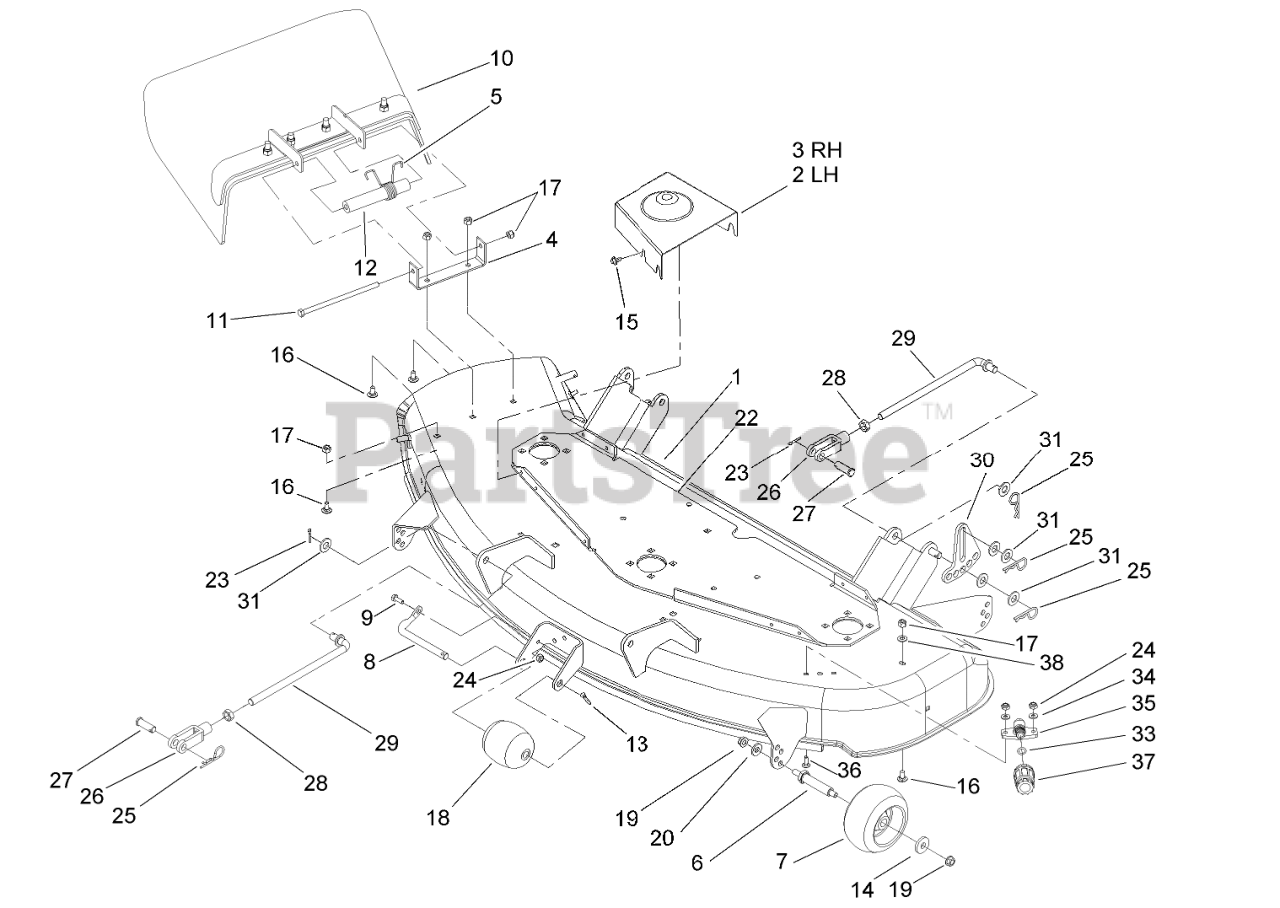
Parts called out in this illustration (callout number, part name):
2	COVER-BELT, LH
3	COVER-BELT, RH
4	BRACKET-PIVOT
5	SPRING-TORSION
8	ROLLER-SHAFT
9	SCREW-HH
10	DEFLECTOR ASM
11	BOLT-HH
12	SPACER-DEFLECTOR
13	PIN-COTTER
14	WASHER
15	SCREW-HHFTF
16	SCREW-CARR
17	NUT-LOCK, NI
18	ROLLER
19	NUT-HHF, WHIZ
20	WASHER-BELLEVILLE
22	PLATE-REINFORCEMENT, DECK
23	PIN-COTTER
24	NUT-LOCK, NI
25	PIN-COTTER
26	CLEVIS
27	PIN-CLEVIS
28	NUT-JAM
30	LINK-HOC, ADJUSTING
31	WASHER-FLAT
33	O-RING
34	WASHER-FLAT
36	BOLT-CARR
37	CONNECTOR-HOSE
38	WASHER-PLAIN
